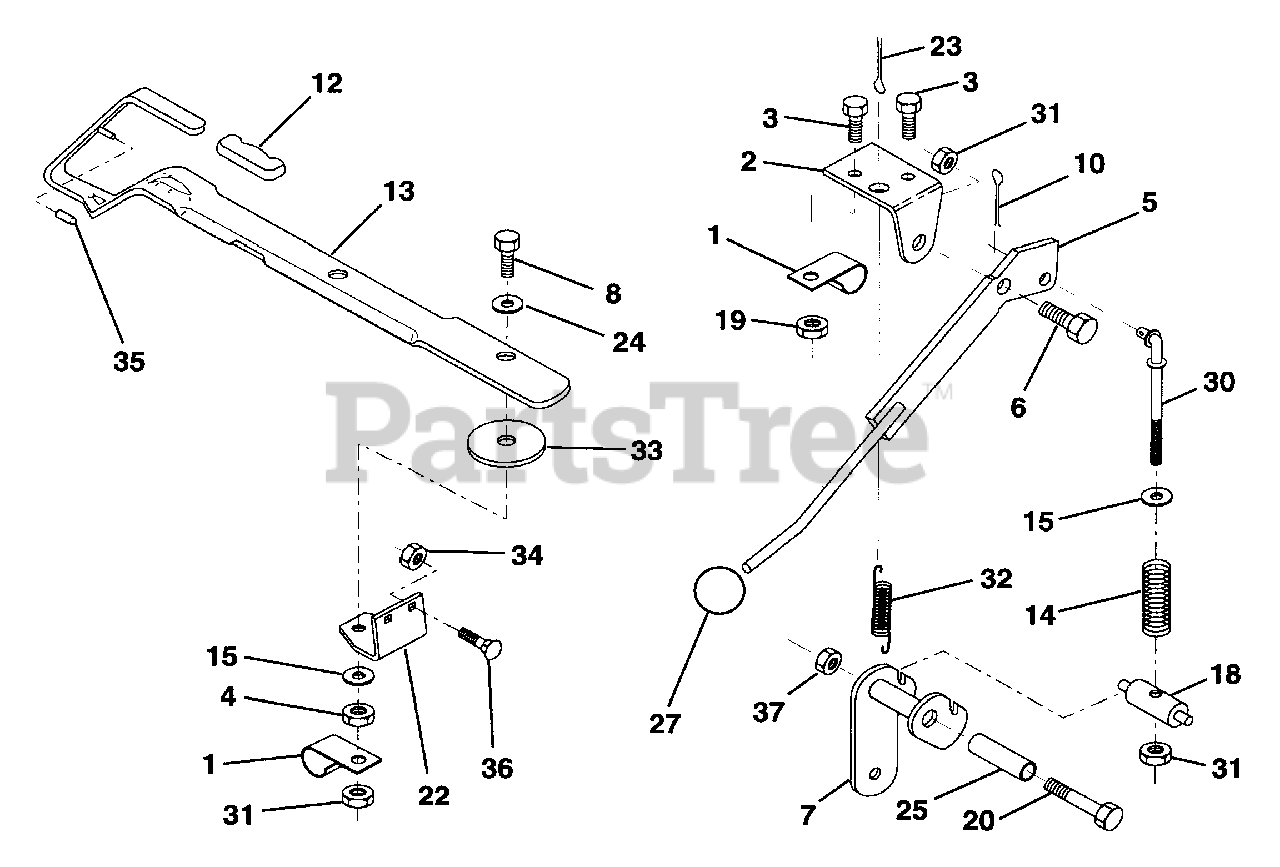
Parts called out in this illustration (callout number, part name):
1	Clip, Insulated
2	Bracket, Mower Clutch
3	Bolt, Hex Head, Fin. 1/4-20 UNC x 1/2 Grade 5
4	Nut, Crownlock 3/8-16 UNC
5	Assembly, Clutch Lever
6	Bolt, Shoulder
7	Assembly, Mower Clutch Arm
8	Bolt, Hex Head 3/8-16 UNC x 1-1/2
10	Pin, Cotter 1/8 x 3/4
12	Handle, Lift Lever
13	Assembly, Lift Handle
14	Spring, Compression
15	Washer 13/32 x 1 x 11 Gauge
18	Trunnion, Threaded 3/8-16
19	Nut, Crownlock 1/4-20
20	Bolt, Hex Head, Fin. 3/8-16 UNC x 2-3/4
22	Bracket, Lift Lever
23	Pin, Cotter 3/32 x 3/4
24	Washer 25/64 x 1-1/4 x 12 Gauge
25	Tube, Spacer
30	Rod, Tension, Clutch
31	Nut, Centerlock
32	Spring, Extension, Return
33	Washer .390 x 1.437 x .074
34	Nut, Crownlock 5/16-18
35	Cap, Vinyl, Red
36	Bolt, Carriage 5/16-18 x 3/4
37	Nut, Crownlock 3/8-16
